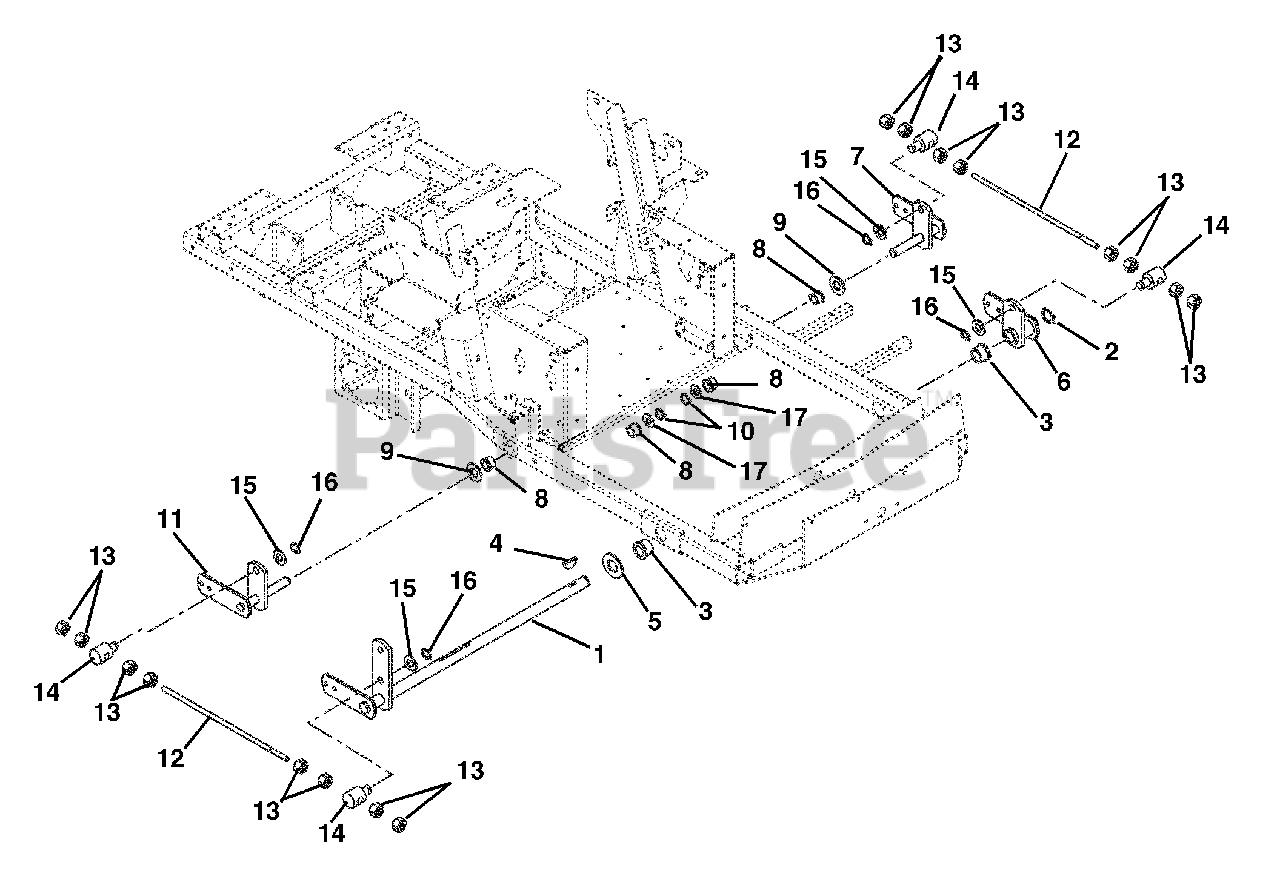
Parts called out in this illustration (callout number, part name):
1	Lift-Mower
2	Ring-Retaining-External 1.00 x .078
3	Bushing-Flange-Nylon 1.020 x 1.385 x .75 x 1.75
4	Key-Woodruff .25 x 1.00
5	Washer-Flat-Steel 1.063 x 2.00 x .134
6	Weldment, Lift Arm-Front
7	Weldment, Rear Lift Arm-Left Hand
8	Bushing-Flange-Nylon .762 x 1.0 x .580 x 1.48
9	Washer-Hardened-Steel .758 x 1.23 x .031
10	Ring-Retaining-External .689 x .077
11	Weldment, Rear Lift Arm- Right Hand
12	Rod-Lift Assist
13	Nut-Jam .50-13
14	Pivot-Mower Lift
15	Washer-Flat-Steel .630 x 1.005 x .062
16	Ring-Retaining-External .625 x 050
17	Washer-Flat-Steel .755 x 1.25 x .125
